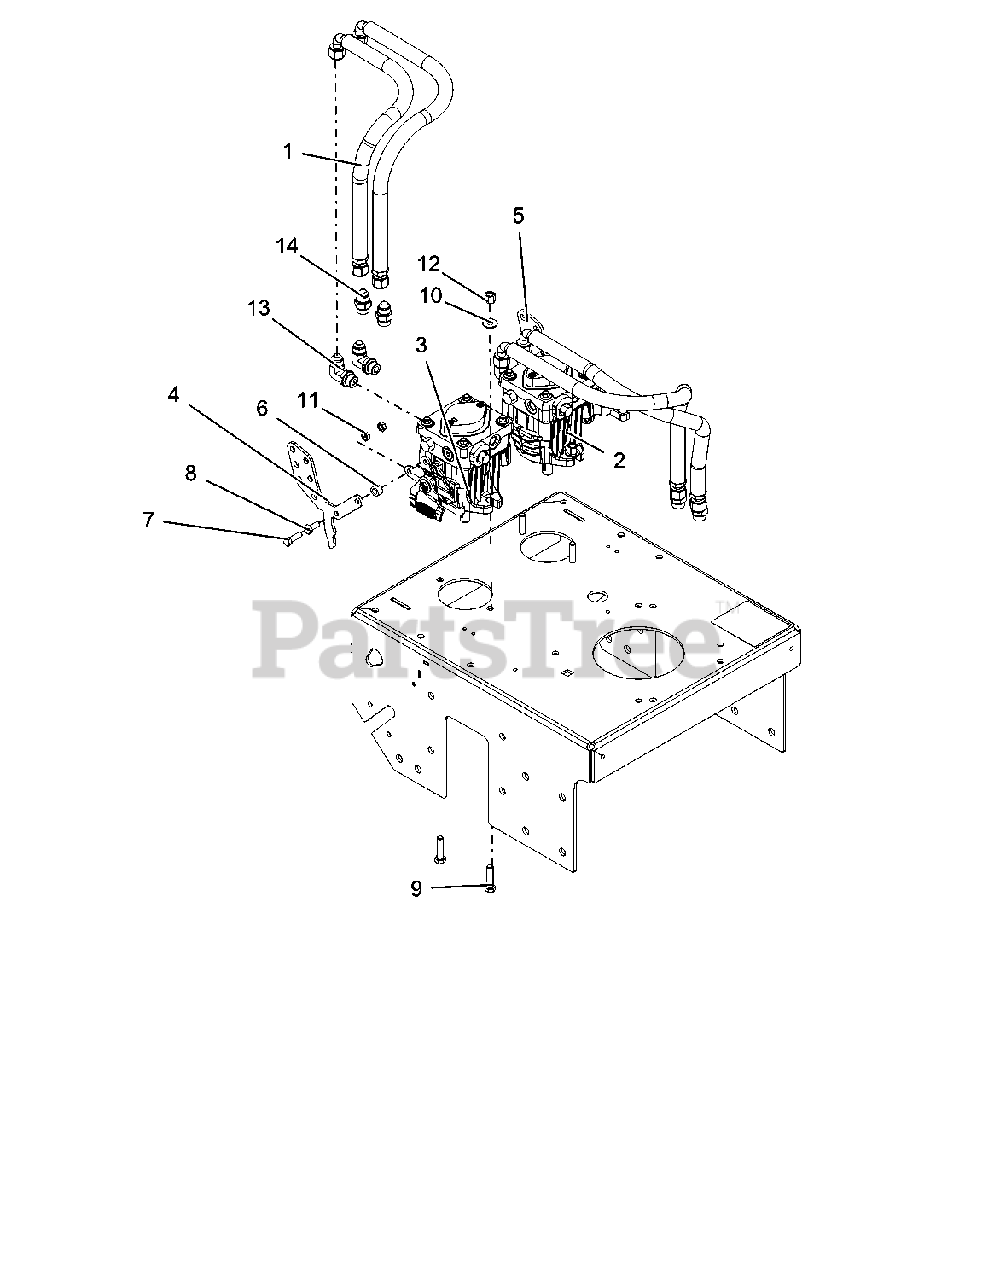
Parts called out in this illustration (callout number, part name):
1	HOSE, HYD 1/2 X 22 1/2 EZFLEX
2	PUMP, LH HYD PE (10CC)
3	PUMP, RH HYD PE (10CC)
4	BRKT, RH PUMP CONTROL WRS
5	BRKT, LH PUMP CONTROL WRS
6	BSHG, SLV REV
7	BLT-HEX .31-18X1.00 GR5 YWZC
8	BLT-HEX .31-18X.75 GR5 YWZC
9	BLT-HEX .38-16X1.50 GR5 YWZC
10	WSHR-FL-STL.38X.875X.083 YWZC
11	NUT-LK-CTR-JAM .31-18 YWZC
12	NUT-LK-NYL .38-16 YWZC
13	FTG, ADP JIC-ORB 6801-08-08
14	FITTING, STRAIGHT
